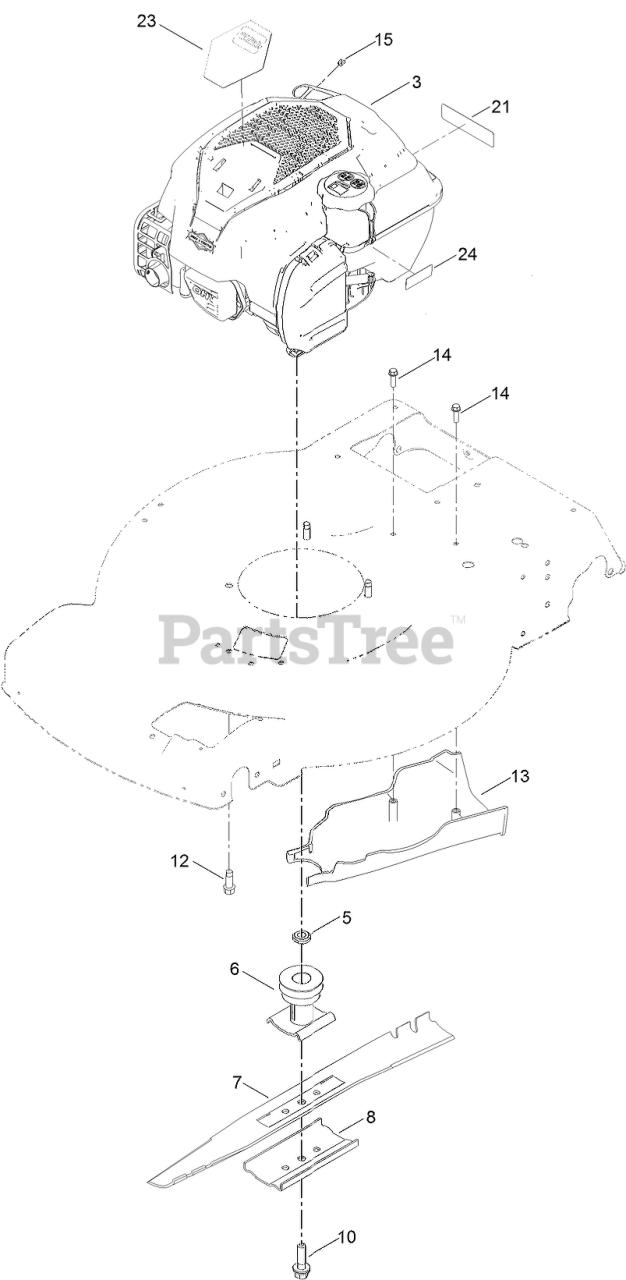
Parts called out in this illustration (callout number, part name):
5	SPACER-DRIVER
6	DRIVER-BLADE
7	BLADE-22 INCH
8	SUPPORT-BLADE
10	BOLT-BLADE
12	SCREW-TAPTITE
13	COVER-BELT, REAR
14	SCREW-HWH
15	STOP-ROPE
21	DECAL-ARRESTOR, SPARK
23	DECAL- B&S SHROUD
24	DECAL-LEVEL, FUEL
